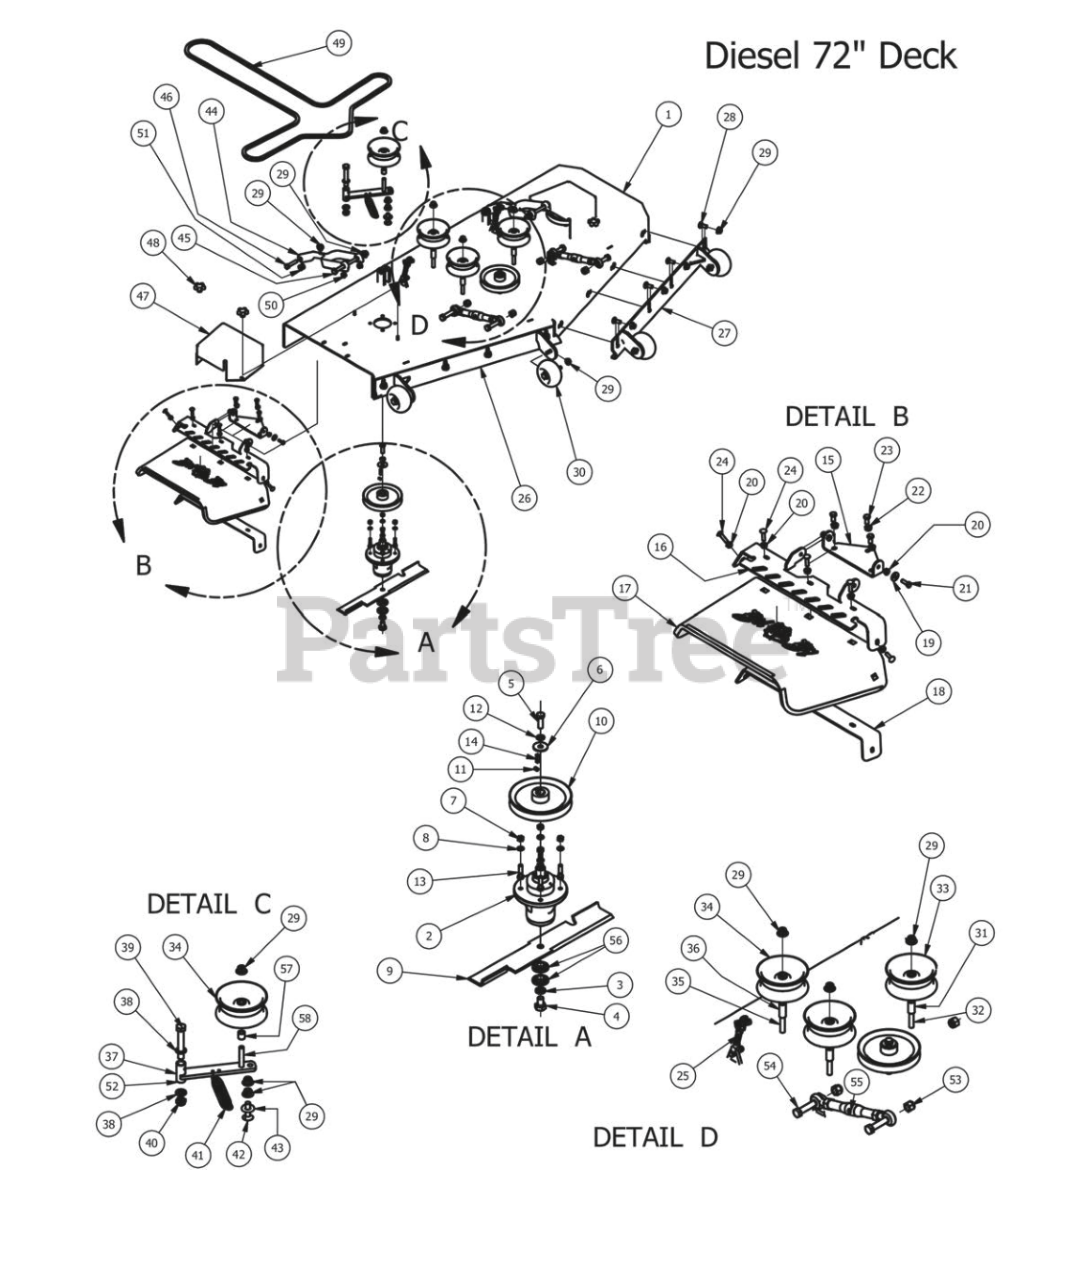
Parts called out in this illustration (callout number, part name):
1	72" (Deck Only)
2	Double Bearing Spindle
3	5/8" Lock Washer
4	5/8" x 1 1/2" Grade 8 Bolt
5	1/2"-20 x 1 1/2 - Grade 5 Fine Thread Bolt
6	1/2 Belleville Washer
7	3/8-16 Hex Nuts Zinc
8	3/8 Lockwasher Zinc
9	72" High Lift Fusion Blade
10	7" Deck Pulley
11	3/8" Set Screw
12	1/2" Lock Washer
13	3/8" x 1 1/2" Hex Bolt
14	1/4" x 1" Key
15	Discharge Chute Hanger (deck mounted)
16	60" Upper Discharge Chute Bracket
17	Rubber Discharge Chute
18	60" Lower Discharge Bracket
19	.360 ID Plastic Washer
20	5/16" Flange Nut Zinc W/Serrations
21	5/16" x 1" Bolt
22	3/8" Flange Nut
23	3/8" x 3/4" Hex Bolt
24	5/16" x 1 1/4" Carriage Bolt
25	5-Link Adjustable Deck Hange
26	72" Deck Adustable Front (Right)
27	72" Deck Adjustable Front (Left)
28	1/2" x 1 1/4 Carriage Bolt
29	1/2-13 Nylon Insert Flange Nut
30	Deck Wheel
31	.502 ID X.75 OD X 1.500 Leng
32	1/2 x 3 1/2 Flange Bolt Grade 8
33	5 3/4" Deck Idler Pulley
34	5 3/4 Flat Idler-32FI-92-008 Pulley
35	1/2" x 4" Bolt (Grade 8)
36	1 3/4" Pulley Spacer
37	Deck Idler
38	.635 ID Plastic Washer
39	5/8" x 4" Hex Bolt
40	5/8" Nylock (1/2 Jam)
41	2009 Deck/Pump Idler Spring
42	1/2 x 2" Carriage Bolt
43	1/2" Flat Washer
44	Deck Arm Assembly
45	1/2" x 5 1/2" Bolt
46	1/2-13X 2-1/4 GR Hex Bolts
47	72 Spindle Cover
48	5/16" Knob
49	B252-50 Fits 2007 72" Diesel
50	Flange Bushing For Deck Arm upper
51	Flange for Lower Deck Arm
52	Deck Idler Complete Assembly- Componets 29,34,37,57,58
53	5/8 Std NC Nylock Nut
54	5/8" x 2 1/2" Hex Bolt
55	Turnbuckle (Top Link)
56	Double Bearing For Spindle
57	3/4 OD x 1/2 ID x 3\4 Length
58	1/2-13 x GR 5 Hex Bolt Zinc
